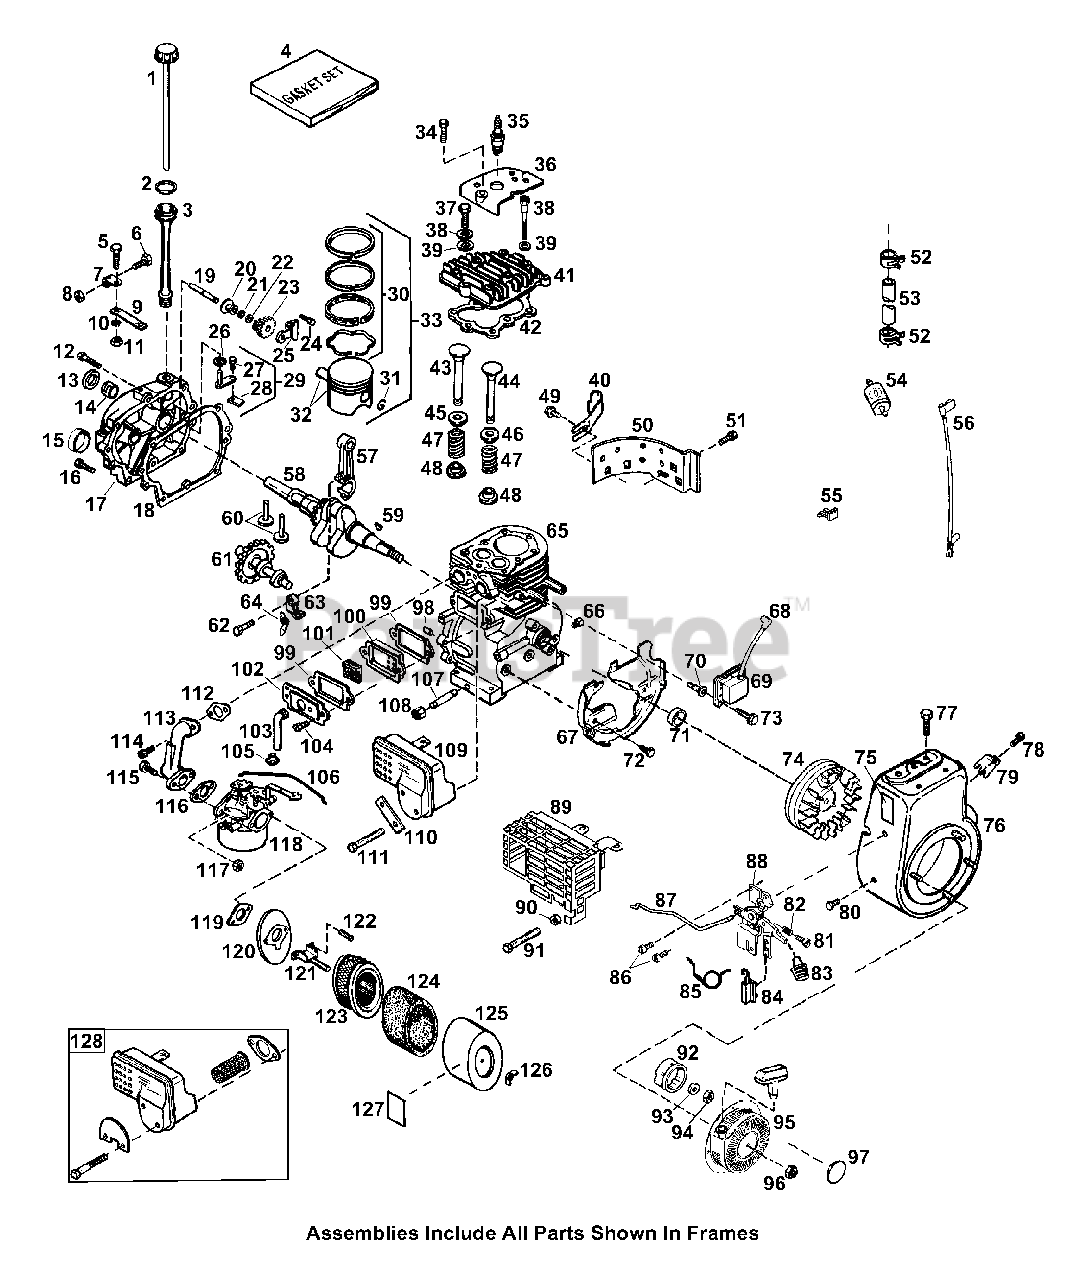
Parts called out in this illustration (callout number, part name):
3	Oil Fill Tube
4	Gasket Set
5	Screw, Torx T-15, 8-32 x 3/8"
6	Screw, 10-32 x 3/4"
7	Governor Lever Clamp
8	Lock Nut, 10-32
9	Governor Lever
10	Lock Washer
11	Lock Nut, 8-32
12	Screw, 1/4-20 x 1-3/16"
14	Crankshaft Bushing
15	Camshaft Seal
16	Screw, 1/4-20 x 1-11/16"
17	Cylinder Cover
18	Cylinder Cover Gasket
19	Governor Shaft
20	Governor Spool
22	Retaining Ring
23	Governor Gear Assy.
24	Screw, 10-24 x 1/2"
25	Governor Gear Bracket
26	Retaining Ring
27	Screw, 6-40 x 5/16"
28	Governor Yoke
29	Governor Rod
30	Ring Set (Std.)
31	Piston Pin Retaining Ring
32	Piston & Pin Assy. (Std.)
33	Piston, Pin & Ring Set (Std.)
34	Screw, 1/4-20 x 5/8"
35	Resistor Spark Plug (RJ17LM)
36	Cylinder Head Cover
37	Screw, 5/16-18 x 2"
38	Belleville Washer
40	Fill Tube Clip
41	Cylinder Head
42	Cylinder Head Gasket
43	Intake Valve (Std.)
44	Exhaust Valve (1/32" OS)
45	Valve Spring Cap
46	Valve Spring Cap
47	Valve Spring
48	Valve Spring Keeper
49	Screw, 10-24 x 1/2"
50	Blower Housing Extension
51	Screw, Torx T-30, 1/4-20 x 1/2"
52	Fuel Line Clamp
53	Fuel Line
54	Fuel Filter
55	Wire Clip
56	Ground Wire
57	Connecting Rod Assy.
58	Crankshaft
59	Flywheel Key
60	Valve Lifter
61	Camshaft (MCR)
62	Connecting Rod Bolt
63	Connecting Rod Assy.
64	Oil Dipper
65	Cylinder
66	Oil Drain Plug
67	Blower Housing Baffle
68	Spark Plug Cover
69	Solid State Ignition
70	Solid State Mounting Stud
72	Screw, 1/4-20 x 5/8"
73	Screw, Torx T-15, 10-24 x 15/16"
75	Throttle Decal
76	Blower Housing
77	Screw, 5/16-18 x 3/4"
78	Screw, 8-32 x 3/8"
79	Starter Bubble Cover
80	Screw, Torx T-40, 5/16-24 x 21/32"
81	Screw, Torx T-10, 5-40 x 7/16"
82	Compression Spring
83	Control Knob
85	Speed Control Spring
86	Screw, 10-32 x 1/2"
87	Governor Link
88	Control Bracket
89	Heat Shield
91	Screw, 5/16-18 x 3-31/32"
92	Starter Cup
93	Lock Washer
94	Flywheel Nut
95	Rewind Starter
96	Nut & Lock Washer, 1/4-28
97	Starter Decal
98	Dowel Pin
99	Valve Cover Gasket
100	Breather Body
101	Breather Element
102	Valve Cover
103	Breather Tube
104	Screw, 10-24 x 1/2"
105	Breather Tube Grommet
106	Throttle Link
107	Oil Drain Extension
108	Extension Cap
110	Locking Plate
111	Screw, 5/16-18 x 3-3/16"
112	Intake Pipe Gasket
113	Intake Pipe
114	Screw, Torx T-30, 5/16-18 x 1-1/8"
115	Screw, 1/4-28 x 1"
116	Carburetor To Intake Pipe Gasket
117	Nut & Lock Washer, 1/4-28
118	Carburetor
119	Air Cleaner Gasket
120	Air Cleaner Body
121	Air Cleaner Bracket
122	Screw, 10-32 x 1/2"
123	Air Cleaner Filter
124	Air Cleaner Filter
125	Air Cleaner Cover
126	Wing Nut, 1/4-20
127	Oil Instruction Decal
128	Spark Arrestor Kit
